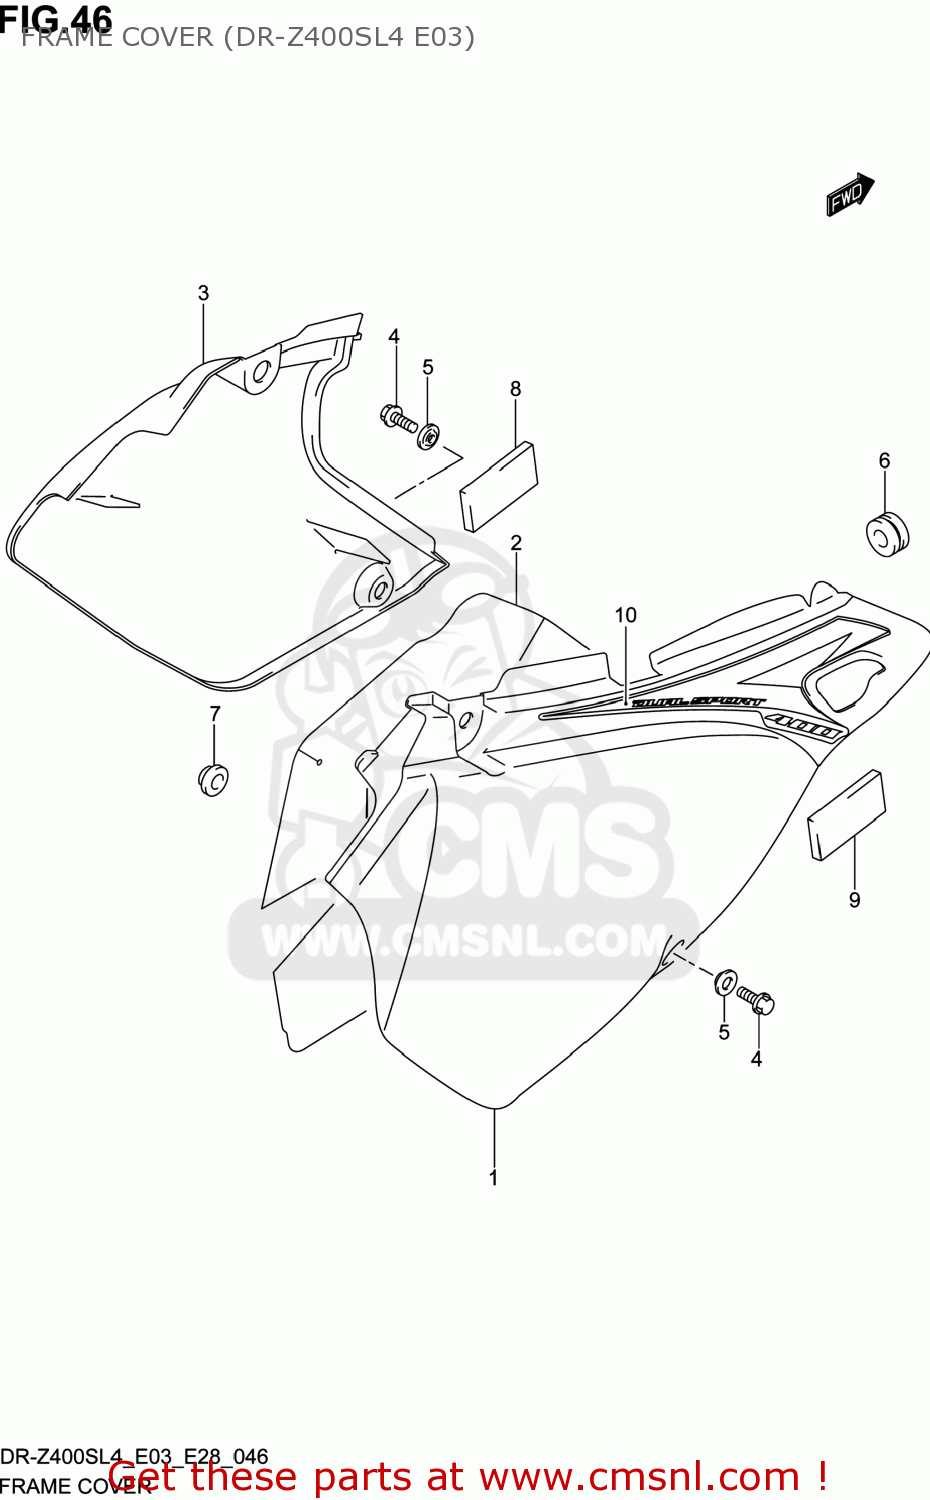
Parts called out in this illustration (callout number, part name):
1	COVER,FRAME,R(BLACK)
2	SHIELD,FRAME COVER,R
3	COVER,FRAME,L
4	BOLT(6X12)
5	WASHER
6	CUSHION
7	CUSHION
8	CUSHION,FRAME COVER,L
9	CUSHION
10	TAPE,FRAME COVER,R
